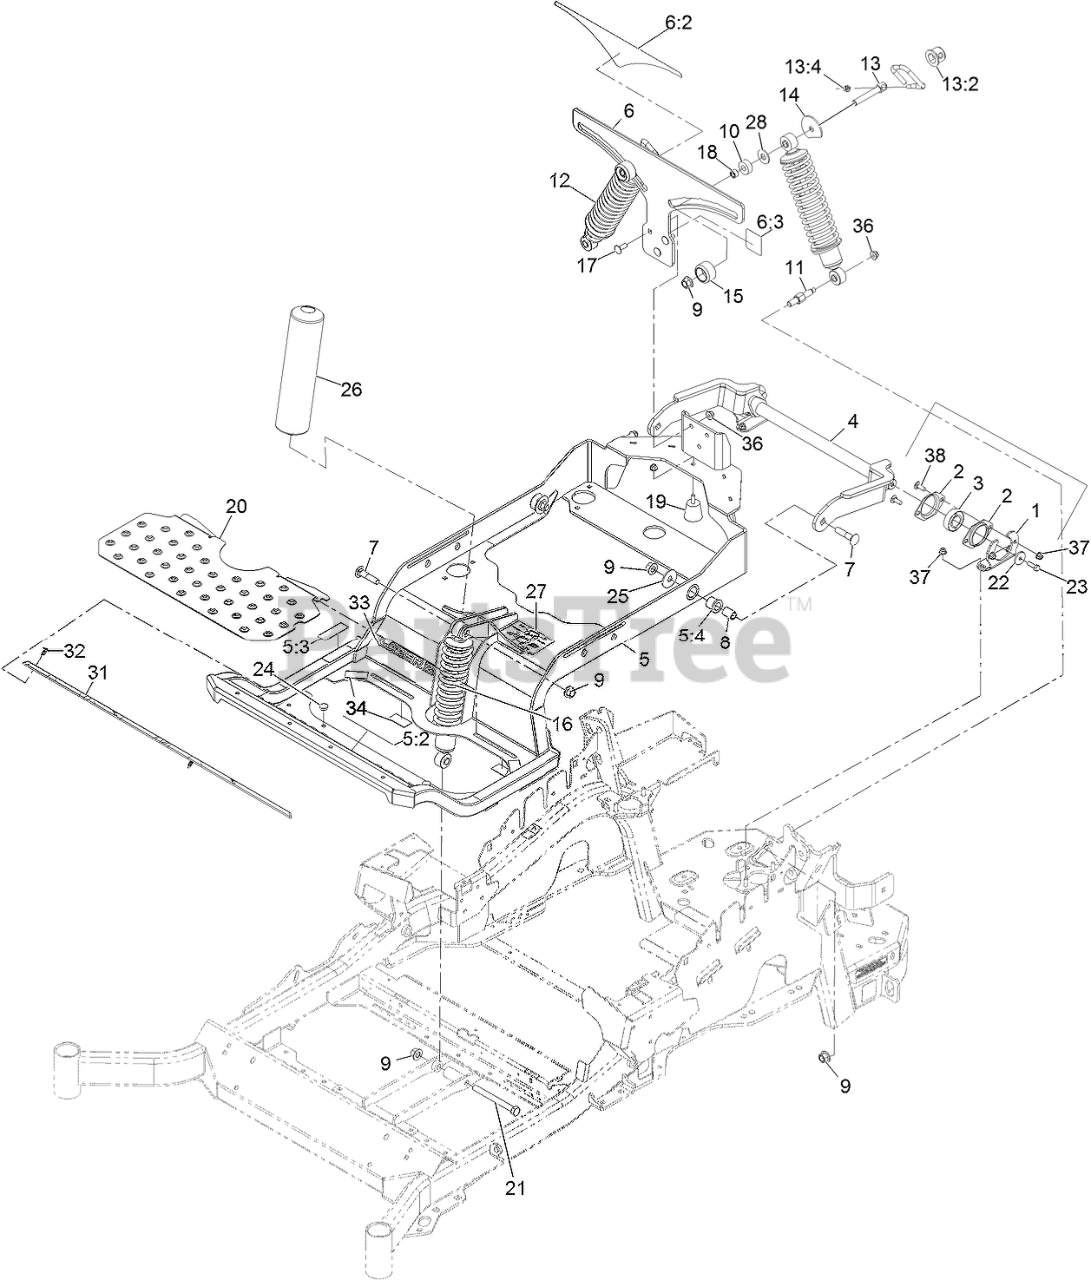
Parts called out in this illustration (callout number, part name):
1	BRACKET-BEARING
2	HOUSING-BEARING, FLANGE
3	BEARING
4	ARM-TRAILING
5	SUBFRAME ASM
5:2	DECAL-DANGER
5:3	DECAL-BRAKE, PARKING
5:4	BUSHING-FLANGE
6	BRACKET-MOUNTING
6:2	DECAL-ADJUSTMENT, RIDE
6:3	DECAL-LOCK, CAM
7	SCREW-CARR
8	SPACER-ALUMINUM
9	Nut-Lock 1/2-13
11	BOLT-SHOULDER
12	SHOCK/SPRING ASM
13	CAM LOCK ASM
13:2	CAP-LOCK
13:4	NUT-HEX
14	PLATE-STOP
15	KNOB-FRONT
16	SHOCK ASM-FRONT
16	SHOCK/SPRING ASM
17	SCREW-CARR
18	BEARING-NEEDLE
19	BUMPER-RUBBER
21	SCREW-HH
22	WASHER-FLAT
23	SCREW-HH, THREAD LOCKING
25	WASHER-THRUST
26	COVER-SHOCK
27	DECAL-SERVICE AID
28	WASHER-FLAT
31	FLOOR MAT
32	PLUG-PLASTIC
33	DECAL-LAZER LOGO
34	PAD-RUBBER
36	NUT-HF, NI
37	NUT-HF, NI
38	BOLT-CARR
